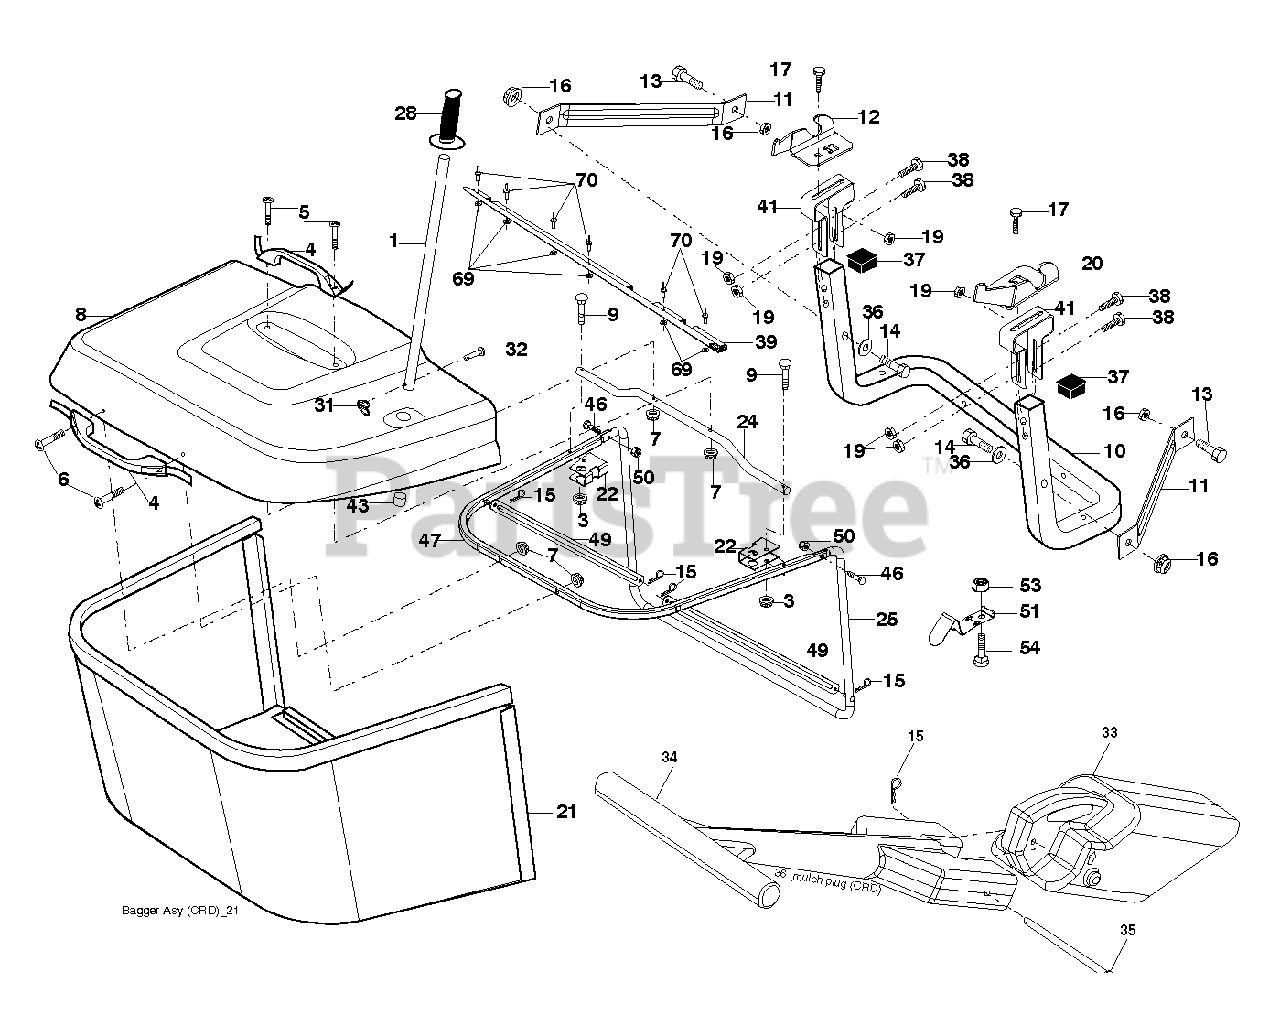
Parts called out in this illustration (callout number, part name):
1	TUBE.PNT.HDL.BAGGER.
3	NUT T
5	SCREW.PAN.HEAD
8	BAGGER.COVER.SEAL.ASM.CRD.428
11	BRACKET
14	BOLT-HEX EAK
15	RETAINER-SPRNG RB
16	NUT LOCK FLG 3/8-16 UNC
17	BOLT
19	NUT LOCK HEX FLANGE 5/16-18
20	BRKT.PIVOT.RH.CRD
21	BAGGER.ASM.CRD.2007
22	BRACKET.BAGGER.SD.
24	TUBE
28	GRIP.HANDLE.BLACK
31	RETAINER CLIP
32	RIVET,DRILLED
33	MULCHING.PLUG.1078.CRD.NON-TEX
35	PIN
38	BOLT.5/16-18X2.5
39	SEAL.BAGGER.CRD
41	BRACKET.BAGGER.SD.
43	PLUG, TUBING END
46	BOLT.CARRIAGE.5/16-18
50	NUT.71038.31-18.HEX.NYLOCK
53	NUT
54	BOLT
